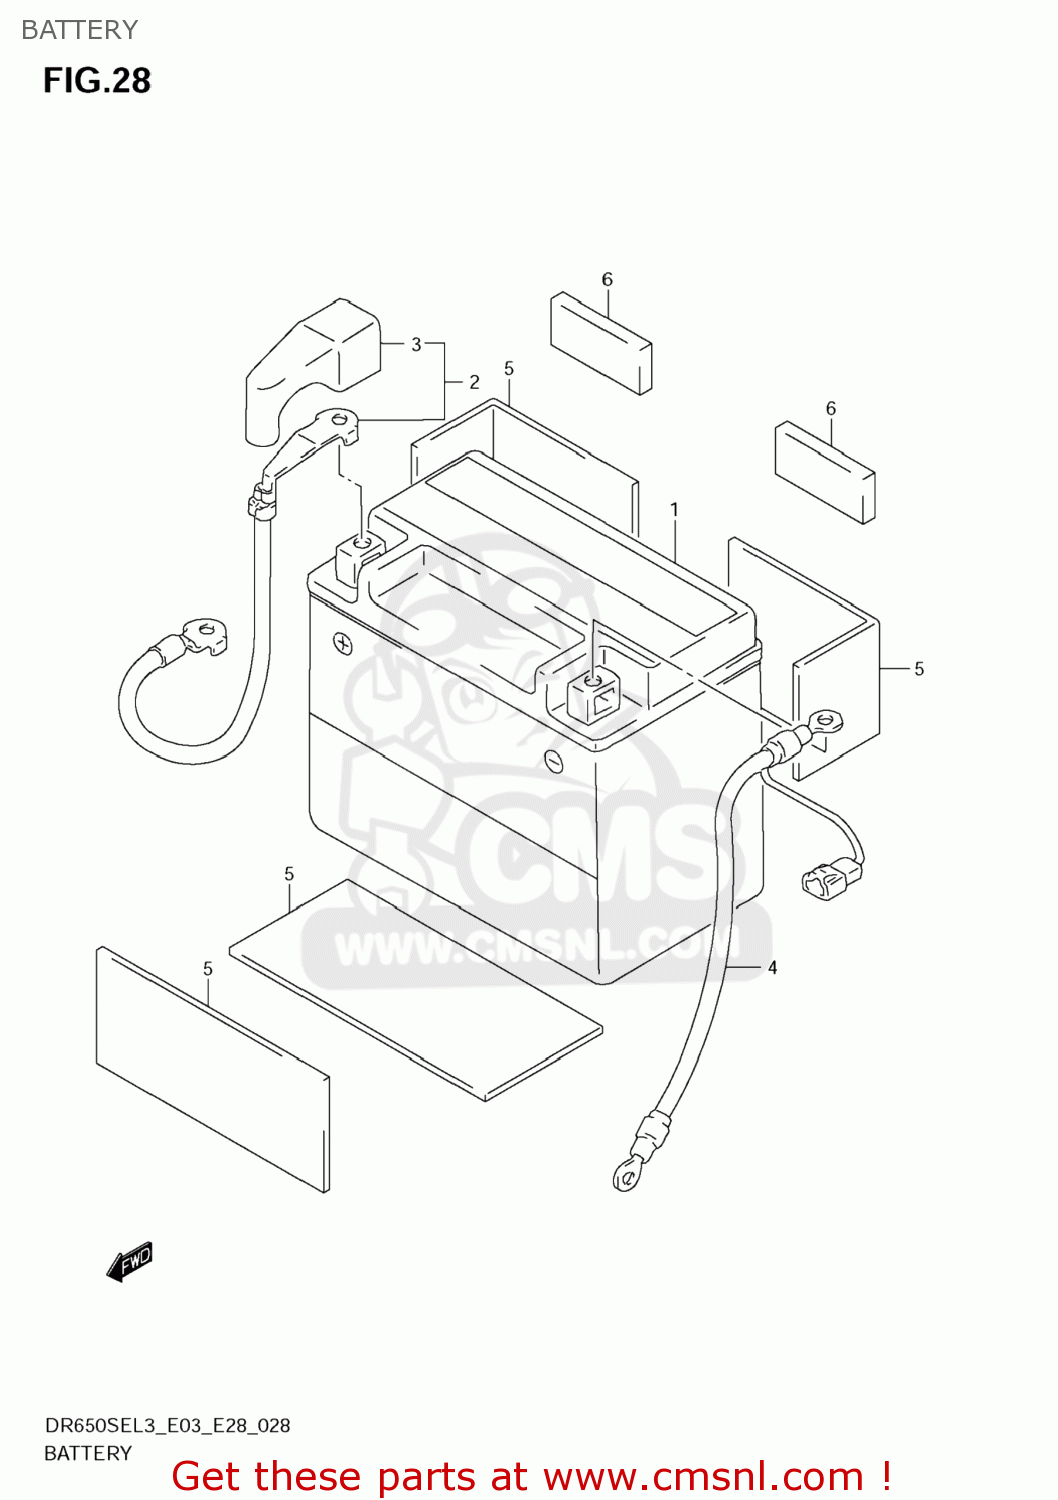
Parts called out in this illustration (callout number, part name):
1	BATTERY ASSY(YTX9-BS,12V8AH)
2	WIRE,BATTERY PLUS
3	CAP,BATTERY PLUS TERMINAL
4	WIRE,BATTERY MINUS
5	PROTECTOR(170X95X3.0)
6	PROTECTOR,BATTERY(70X100X6)
